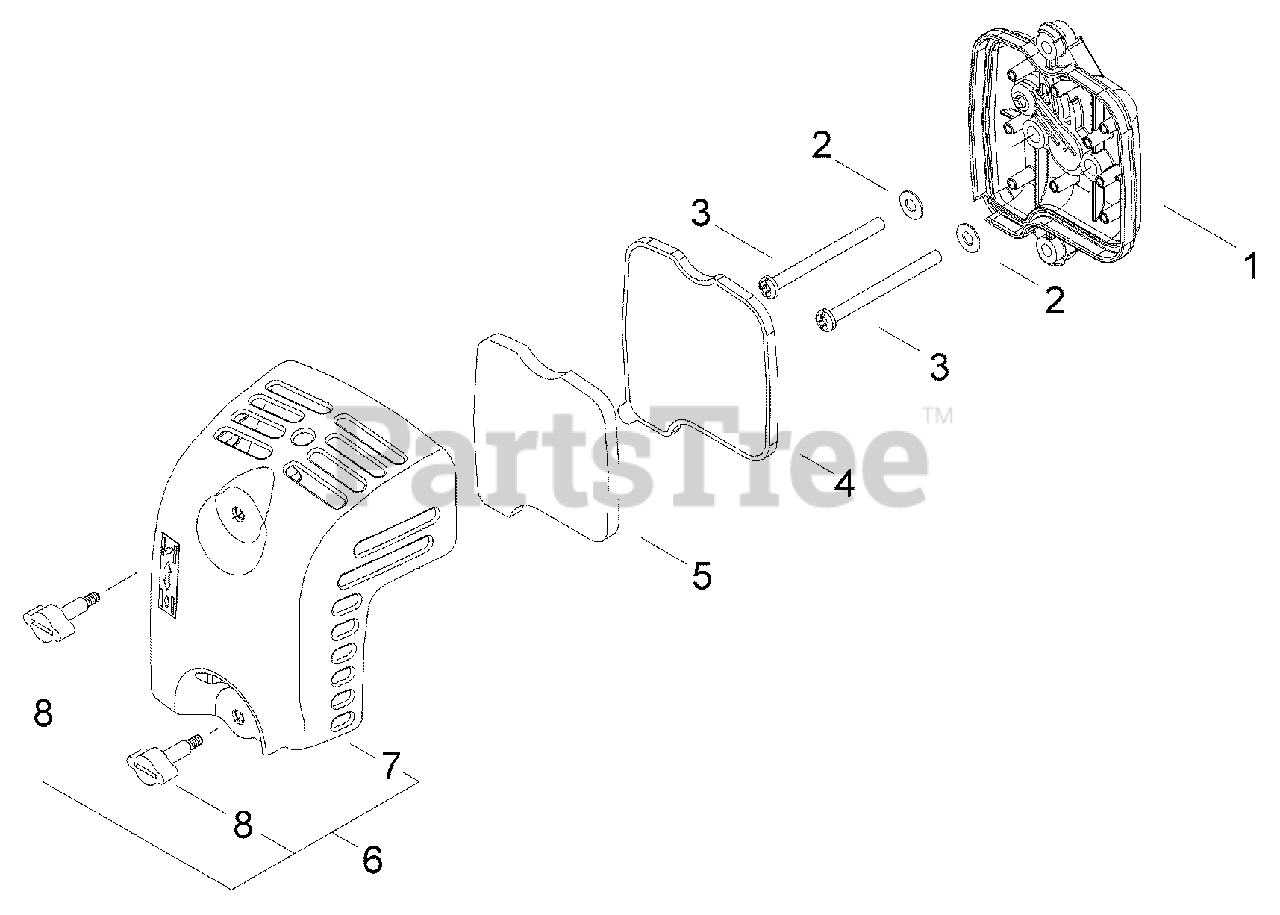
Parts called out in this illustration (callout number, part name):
1	AIR FILTER CASE ASSY
2	WASHER - 5
3	SCREW - 5X60
4	FILTER, AIR
5	PRE-FILTER - FOAM
6	AIR FILTER COVER ASSY
7	COVER, AIR FILTER
8	THUMBSCREW
